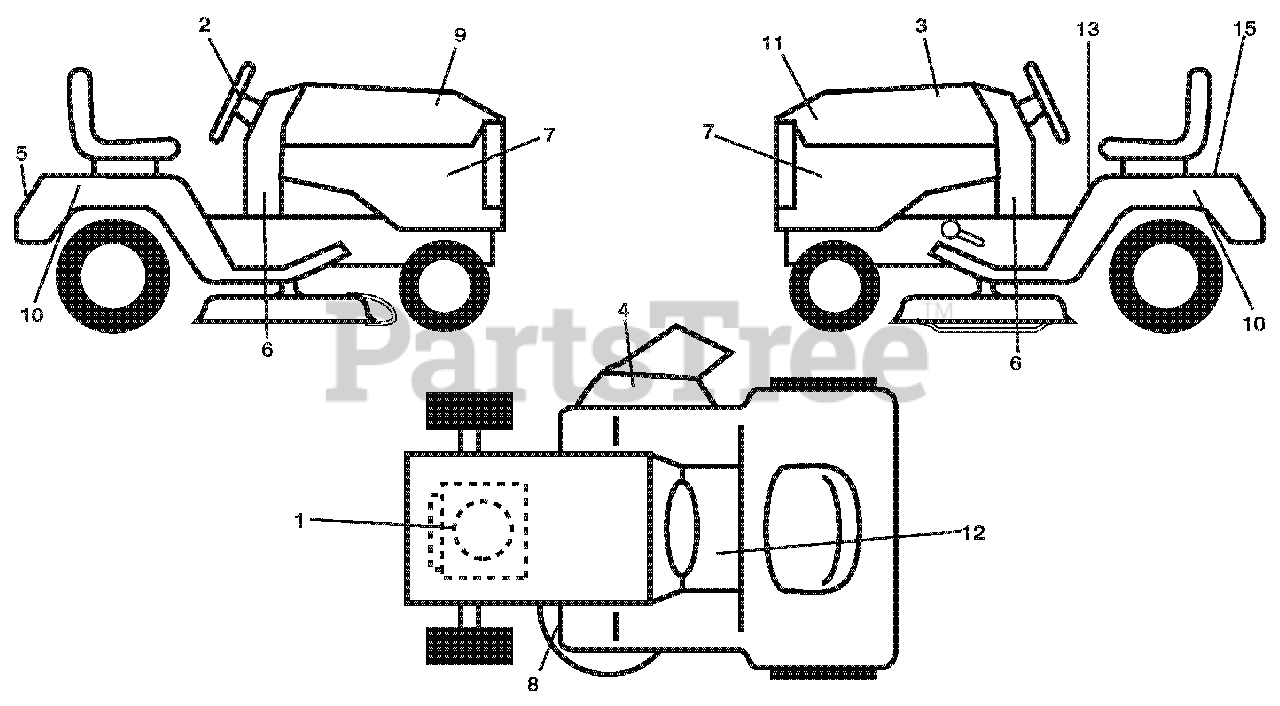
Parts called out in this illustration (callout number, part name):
1	DECAL, REPLACEMENT
2	Decal, Ins Str Wh
3	DECAL.REPLACEMENT
4	DECAL.MOWER.WARN.KEEP HAND AWY
5	DECAL.FENDER.REAR.ARIENS
6	DECAL, DASH LOWER
7	DECAL.SDPNL.PWRDBY B&S.ARIENS
8	DECAL.V-BELT.SCH.42/46"MEC/ELE
9	DECAL.HOOD.RH
10	DECAL.FENDER.SD.GEAR.DR
11	DECAL.HOOD.LH
12	DECAL.FENDER
13	DECAL, WARNING START INST.
15	DECAL.BAT.DAN/POI P/L SYM.WPN
